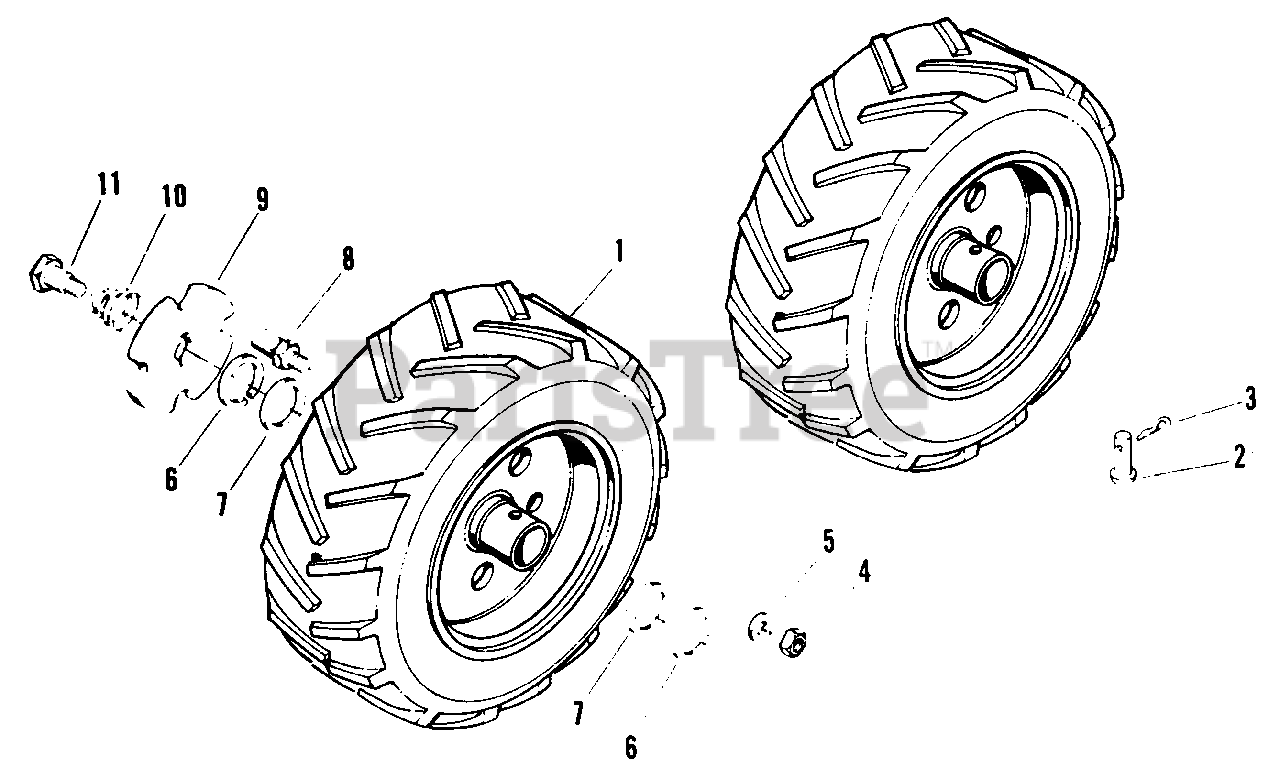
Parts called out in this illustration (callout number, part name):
1	WHEEL & TIRE ASSY.
2	PIN
3	CLIP, Spring
4	LOCKNUT, Hex, 3/8-16
5	WASHER, Plain, 5/16
6	RING, Retaining
7	WASHER, Special
11	BOLT, Shoulder
